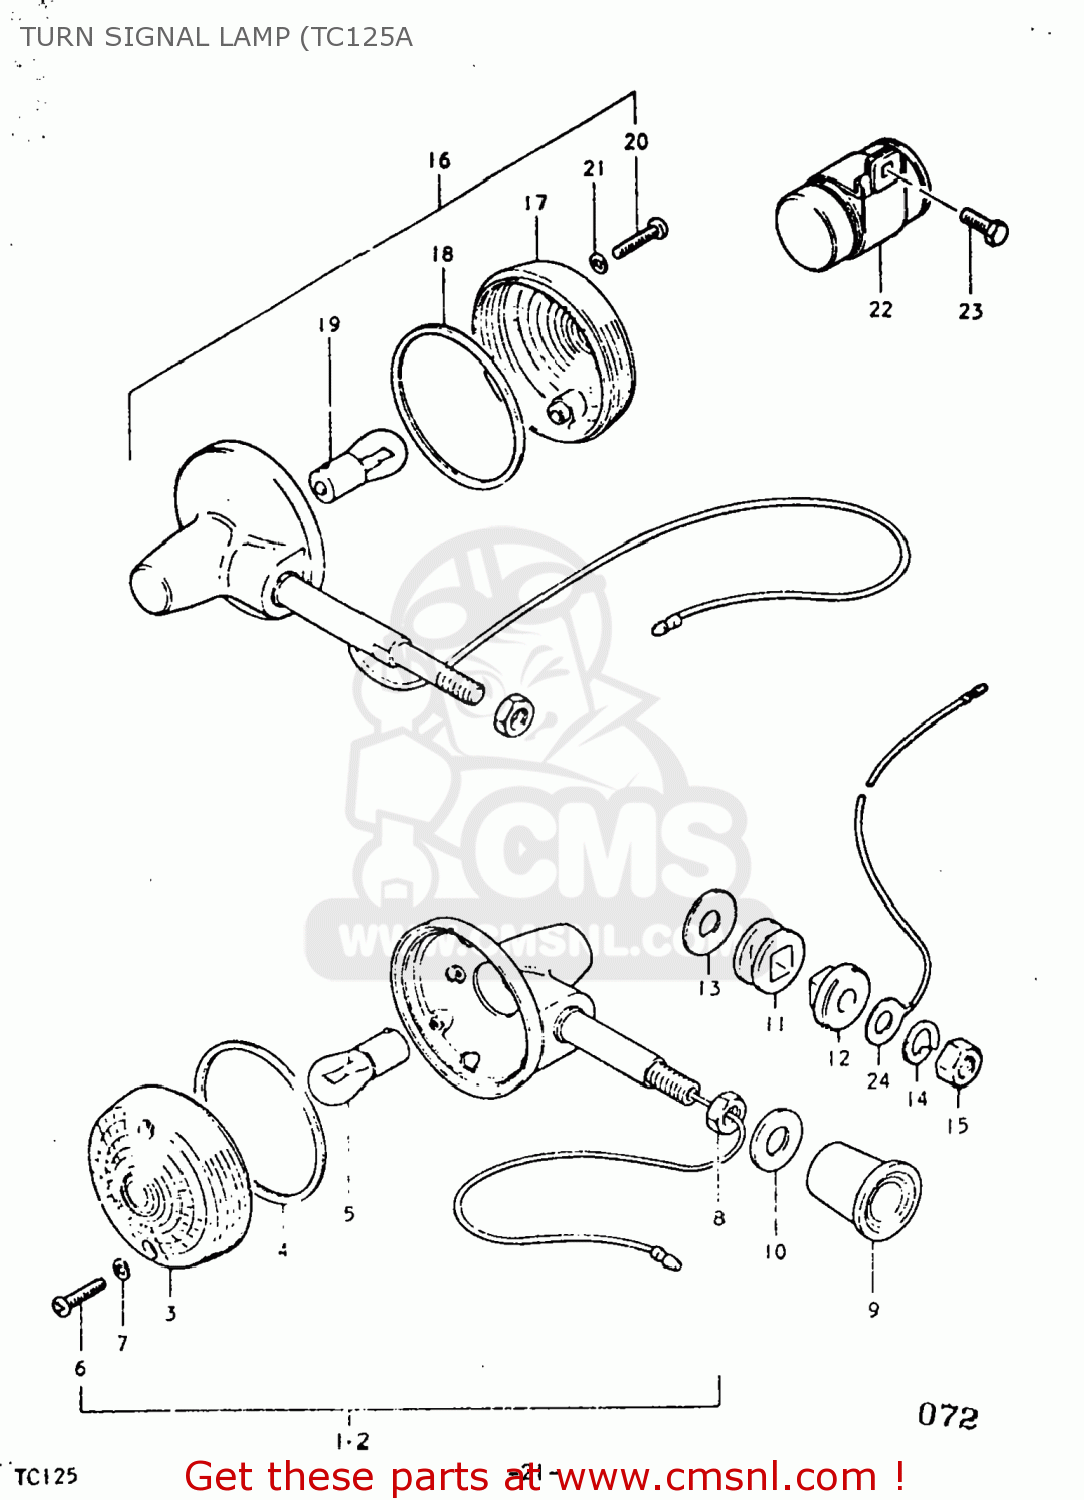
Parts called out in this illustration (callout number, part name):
1	LAMP ASSEMBLY,FRONT TURN SIGNAL
2	LAMP ASSEMBLY,FRONT TURN SIGNAL
3	LENS
4	LENS
5	BULB(6V17W,STANLEY,A4513A)
6	SCREW
7	GASKET (NAS)
8	NUT
9	COVER,FRONT TURN SIGNAL BRACKET
10	WASHER
11	CUSHION
12	SPACER,RR TURNSIGNAL LAMP
13	WASHER (10.5X30X2.3)
14	LOCK WASHER
15	NUT
16	LAMP ASSEMBLY,REAR TURN SIGNAL
17	LENS
18	GASKET (NAS)
19	BULB(6V17W,STANLEY,A4513A)
20	SCREW
21	GASKET (NAS)
22	RELAY,TURN SIGNAL
23	BOLT
24	LEAD WIRE,EARTH
